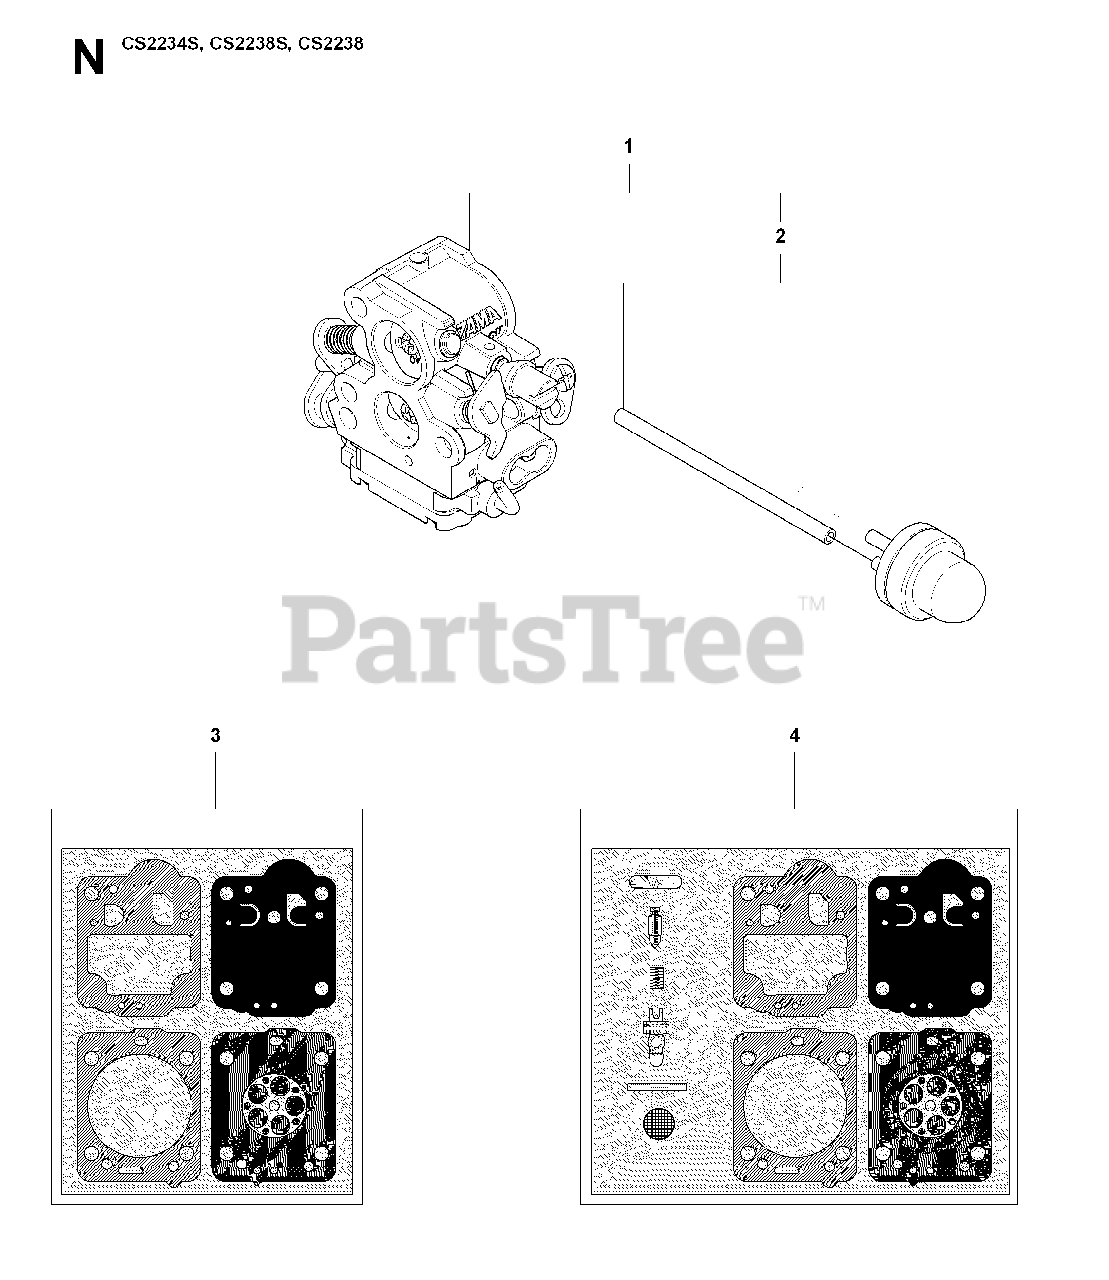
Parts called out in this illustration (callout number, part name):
1	%CARBURETOR
2	PURGE & LINE ASSY
3	KIT CARB GASKET
4	KIT CARB REPAIR
